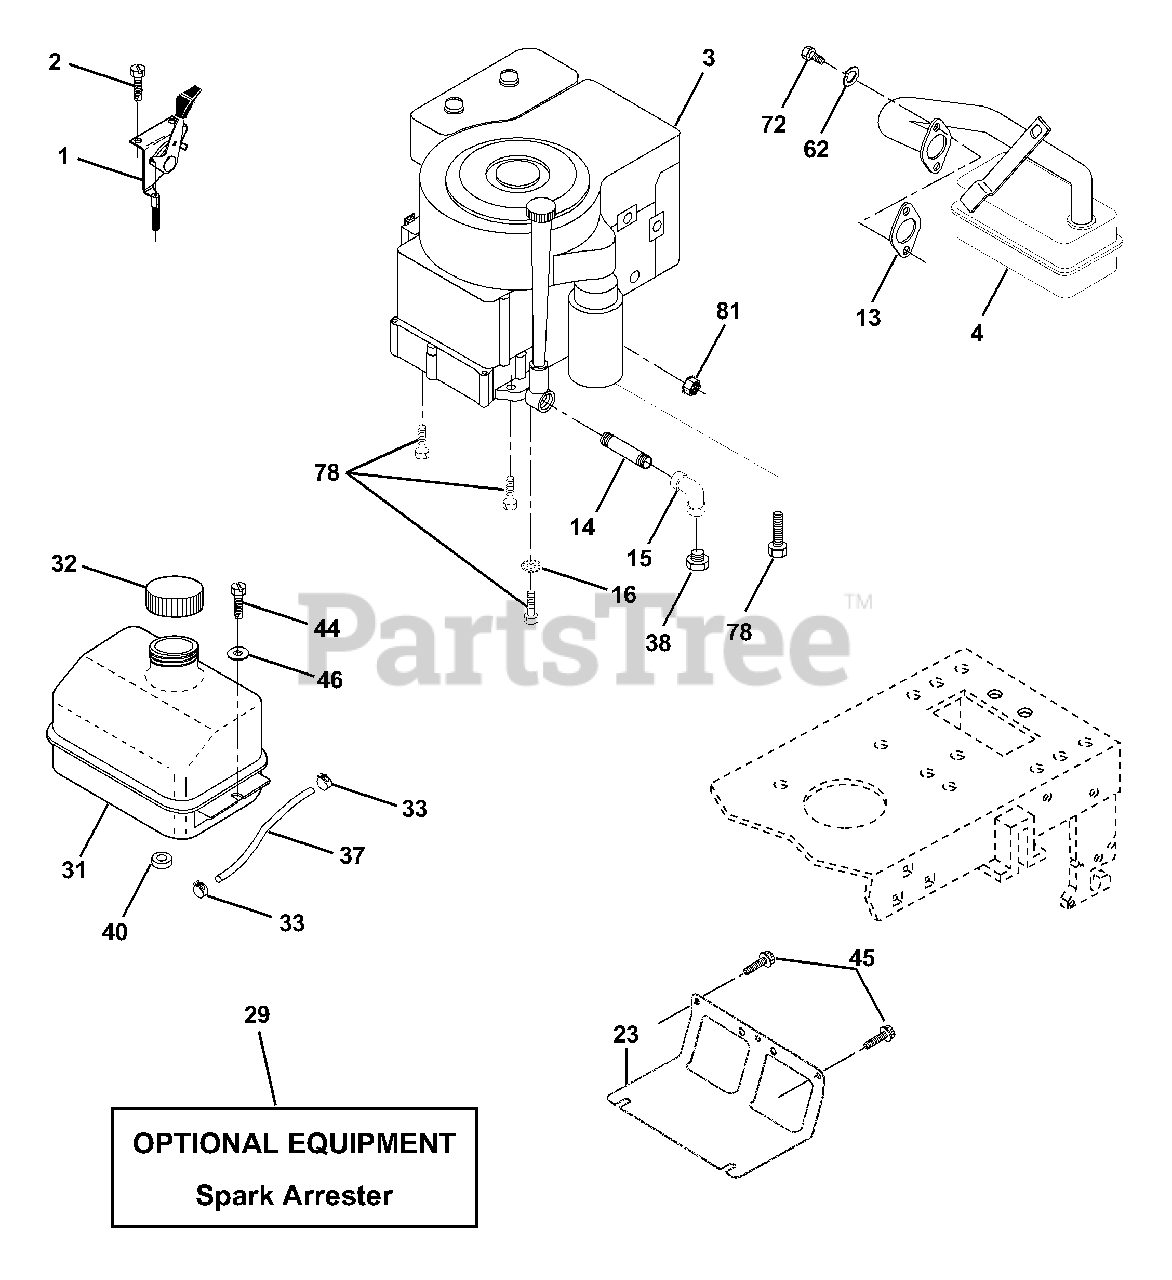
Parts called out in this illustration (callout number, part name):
1	Control Th/ch 23 5 LH Flag
2	Screw Hex Thd Cut 1/4-20x5/8 T
3	Engine, Briggs 289707 (Order parts from engine manufacturer)
4	Muffler LT B&S 12/12.5/13HP
13	Gasket Eng 1 313 Id Tin Plated
14	Nipple Pipe 3/8 Npt x 3"
15	Elbow Std 90 Degree 3/8-18 Npt
16	Washer Lock Ext Tooth 3/8
23	Shield Brn/Dbr Guard
29	Kit Spark Arrestor (Flat Scrn)
31	Tank Fuel Front
32	Cap Asm Fuel W/sym Vented
33	Clamp Hose Black
37	Line Fuel 20"
38	Plug Oil Drain (Order From Engine Manufacturer)
40	Bushing Snap Nyl Blk Fuel Line
44	Screw Hexwsh Thdrol 1/4-20 x 3/4
45	Screw
46	Washer 9/32 x 7/8 x 16 Ga
62	Washer Lock Hvy Hlcl Spr 5/16
72	Screw Hexhd Cap 5/16-18 x 5/8
81	Nut Flange 1/4-20 Starter Nut
